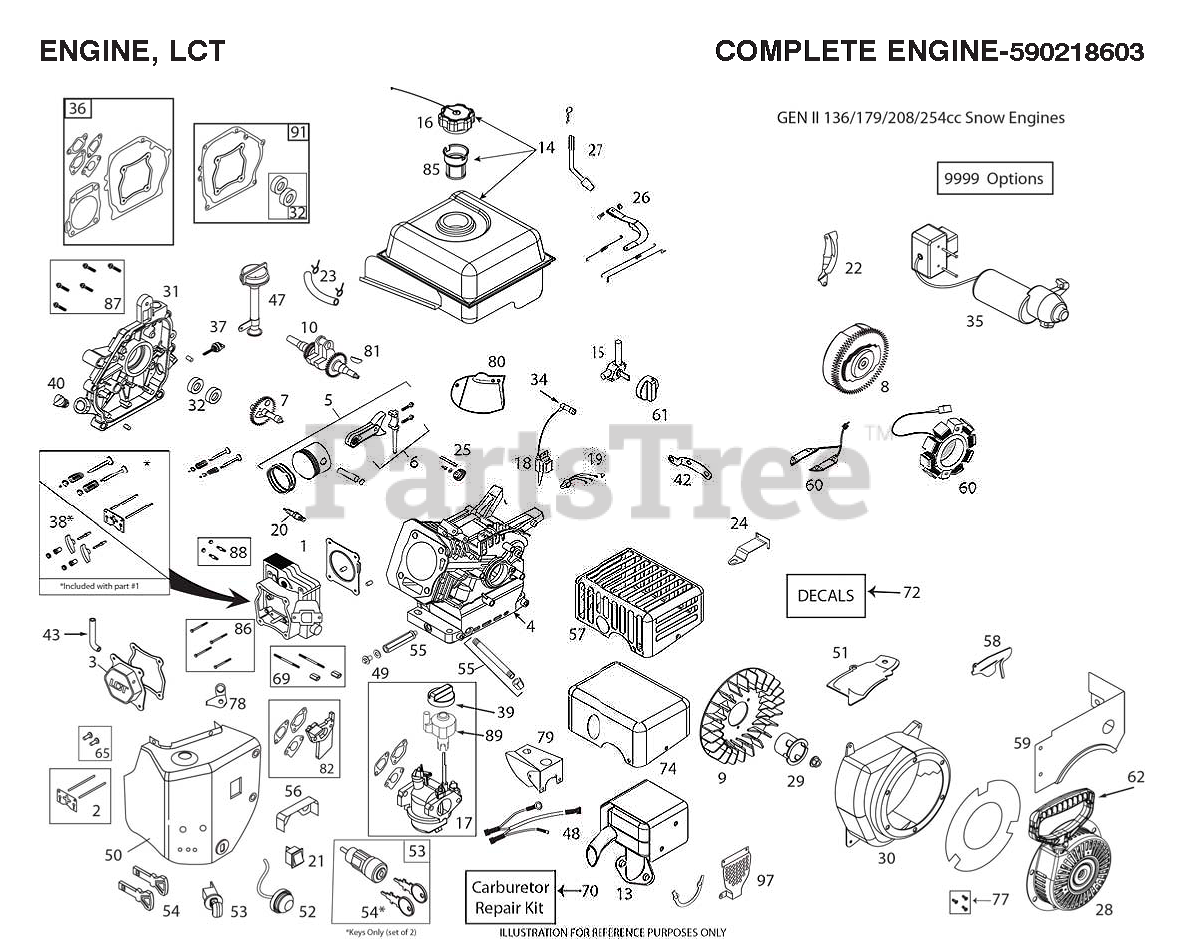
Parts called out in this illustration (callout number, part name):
1	CYLINDR.HEAD.SRV.KIT W/GASKET
2	KIT.PUSH.ROD.SRV(SK208-1001)
3	VALVE COVER ASSEMBLY
5	KIT.PISTON.SRV(SK208-1400)
7	KIT.CAMSHAFT.208CC.LCT
8	FLYWHEEL ELECTRIC START W/6 MA
9	FLYWHEEL FAN 420586
10	CRNKSHFT-KYD#14.208CCSKSNO8001
13	MUFFLER KIT LCT SKSN2205.1
14	FUEL.TK.ASSY.GENII.SKSN0311.1
15	FUEL.PETCOCK.SNOW(SKSN4900)
16	FUEL CAP OVERSIZED CLICK STYLE
17	CARBURETTOR L10-1D.W/SP
18	COIL.ING.CDI.HI TEMP.SKSNO416.
20	SPARK.PLUG(2083810)
22	SHIELD.FLYWHEEL.ELEC.STRT.208C
23	FUEL HOSE KIT
24	SPEED.CTRL.BRKT.(SKSN0150)
25	GOVENOR.GEARS ASM(SK2082900)
26	CARBURETTOR GOVERNOR LINK.ASM.
27	KIT.GOVERNOR.CRANK(SK208-3100)
28	RECOIL.STRT.ROUND(BLK) SNOW
29	STRTER.CUP(NON-SLOT)SKSN0601.2
30	BLOWER HOUSING ASSY
31	COVER CRANKCASE.LCT.SK2083605
32	SEAL KIT (2 PCS)
34	SPARK.PLUG.BOOT.SNW,SKSN4691.1
35	ELEC.START.GEN2.SKSN0451.1
36	GASKET.KIT.208CC(SK2084300.1)
37	DIPSTICK SMALL
38	ROCKER ARM KIT
39	CHOKE.KNOW.SNOW(SKSN4500)
40	NON REMOVABLE PLUG
43	TUBE.BREATHER.LCT.208
47	TUBE ASSY HIGH OIL-FILL
48	HARNESS WIRE. W/O OFF/ON SWITC
49	KIT.OIL.DRAIN.PLUG(SK2089911
50	BOX HEATER.W/O OFF/ON SWITCH.L
51	SHIELD.CYLINGER.LCT.SKSN0608.1
52	PRIMER.BULB.WITH HOSE (SNOW)
53	SWITH.KEY.ASSEM.SNOW.SINGLE.ST
54	KEY SET(2 KEYS) SKSN0407.1
55	EXTENDED OIL DRAIN TUBE
58	SHIELD GOVENOR & CARB - COMPOS
59	FUEL.TNK.SKRT.GENII.SKSN0103.1
60	208CC 60W ALTERNATOR
61	FUEL KNOB-SNOW
65	TAPPET.KIT.LCT.208CC
69	CARB.STUDS & COUPLING KIT.SNOW
70	CARBURETOR.REPAIR KIT.LCT.
74	MUFFLER GUARD.EUR./LCT.SKSN220
77	BOLT.KIT.RECOIL.LCT.ALL.ENGINE
81	KEYS.FLYWHEEL.208/414CC.5PACK
82	SPACER.CARBURETOR.208CC.LCT
85	STRAINER.FUEL.TANK.LCT.208CC
86	BOLT KIT.CYLINDER HEAD.LCT(4)1
87	KIT.BOLT.CRANKCASE.COVER.6PC
88	STUD.MUFFLER.KIT.LCT
91	COVER CRANKCASE GASKET
97	MUFFLE MANIFOLD GUARD.LCT
9999	HIGH.ALTITUDE.JET 6,000FT
9999	STARTER SCREW.STARTER SWITCH B
9999	KIT.BOLT.LCT.SK9990.1
